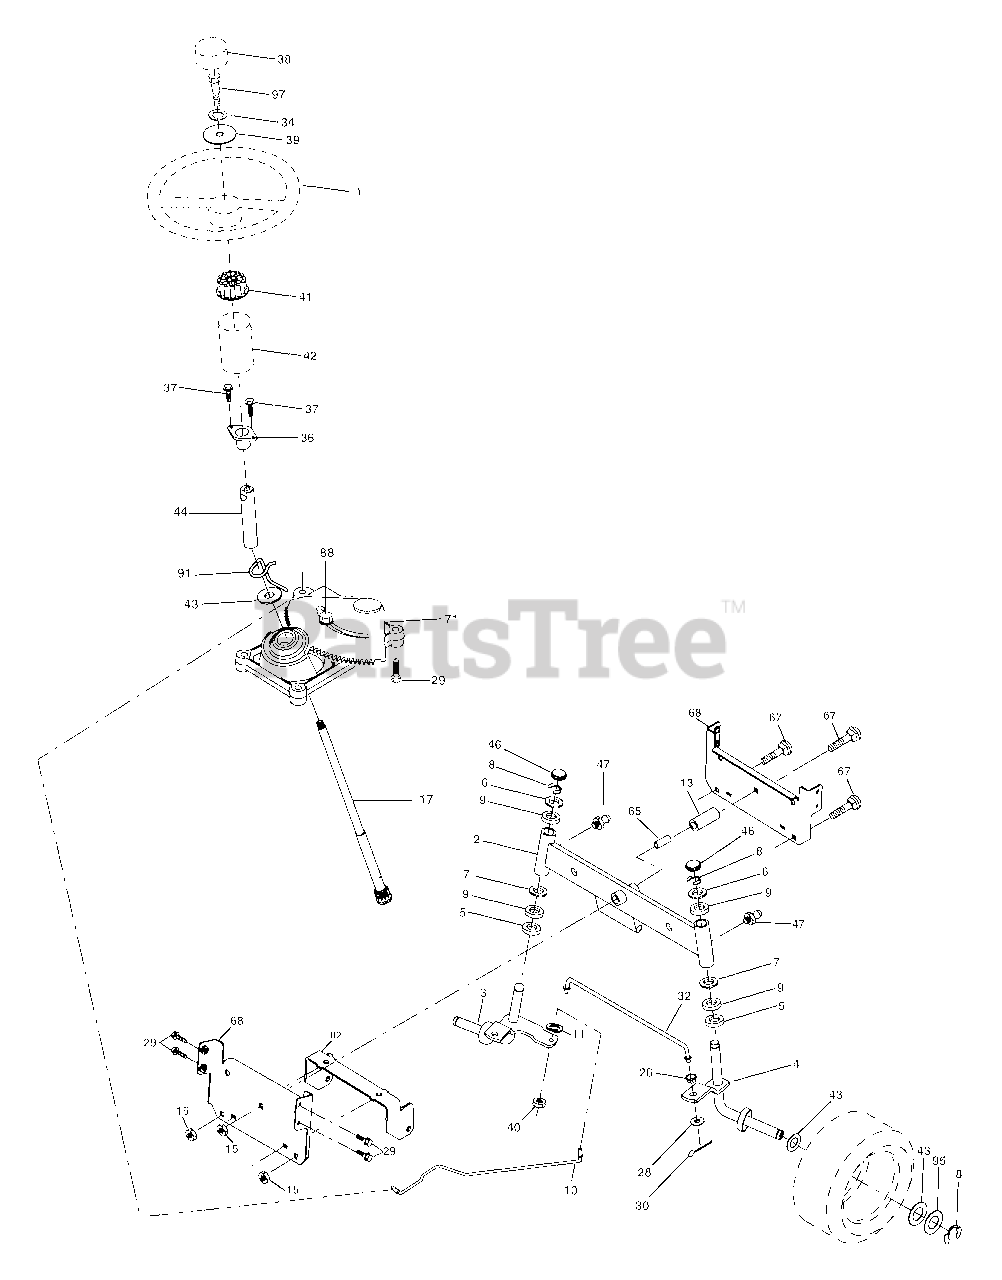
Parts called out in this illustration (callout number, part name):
1	Wheel Steering
2	Axle Asm Front
3	Spindle Asm Lh
4	Spindle Asm Rh
5	Bearing Race Thrust Harden
6	Washer 25/32 x 1 5/8 x 16 Ga.
7	Washer 27/32 x 1 1/4 x 16 Ga.
8	Ring Klip #t5304-75
9	Bearing Col Strg Blk
10	Link Drag Extended
11	Lockwasher
13	Spacer Bearing Axle Front
15	Hex Flange Lock
17	Shaft Asm Strg
26	Bushing Rod Tie Blk Lt
28	Washer 13/32 x 7/8 x 16 Ga.
29	Screw 3/8-16 x 3/4
30	Pin
32	Rod Tie Wire Form
34	Washer Lock Hvy Hlcl Spr. 5/16
36	Bushing Strg 5/8 Id Dash
37	Screw TT #10-32 x 5 x 3/8 Flange
38	Insert Cap Strg
39	Washer 11/32 ID x 2-3/8 OD 12 Gr.
40	Nut Crownlock
41	Adaptor Wheel Strg .760
42	Boot Dash Steering
43	Washer 25/32 x 1 1/4 x 16 Ga.
44	Extension Steering
46	Cap Spindle Fr Top Blk
47	Fitting Grease
65	Spacer Brace Axle
67	Bolt Rdhd Sq 3/8-16 unc x 2-1/4
68	Brace Axle
71	Steering Asm
82	Bracket Susp Chassis Front
88	Bolt Shoulder 7/16-20
91	Clip Steering
95	Washer Hardened
97	Bolt 5/16-18 unc x 4" L Gr. 5
